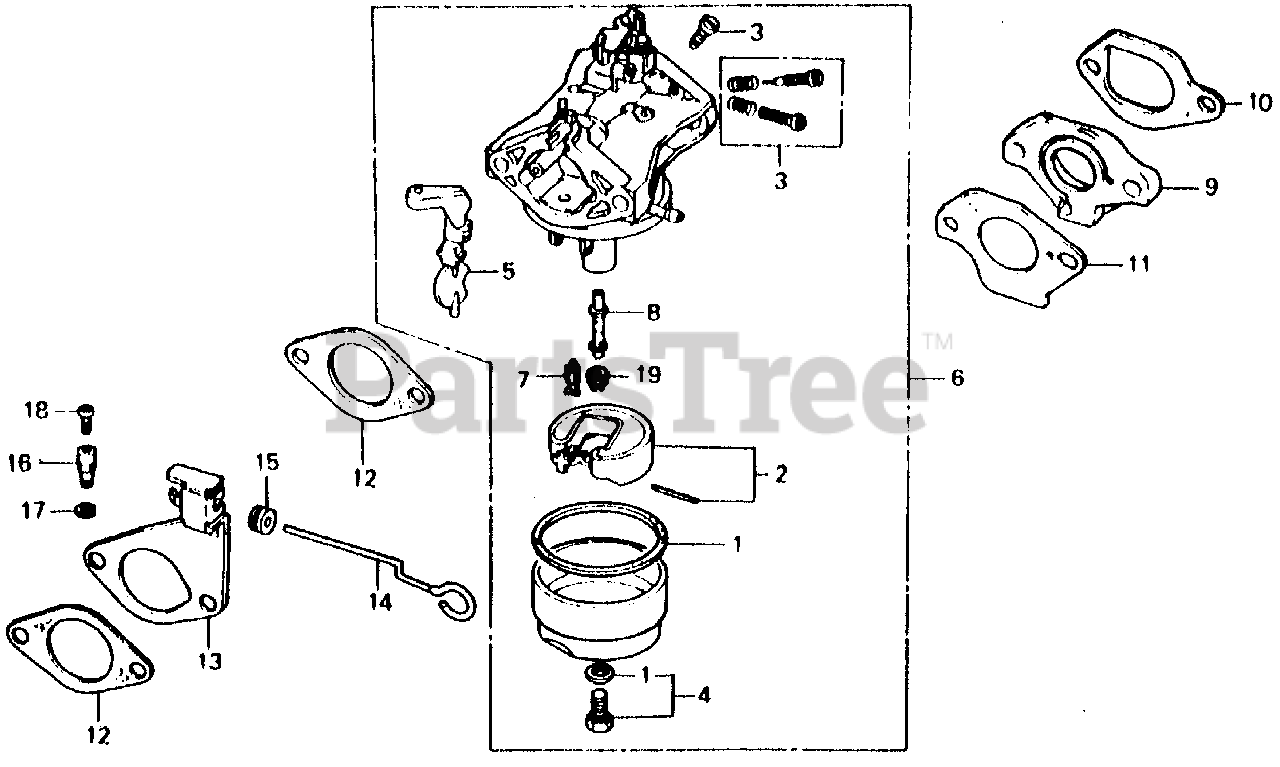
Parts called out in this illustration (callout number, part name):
1	GASKET SET
3	SCREW SET A
3	SCREW SET A (NOT AVAILABLE)
4	SCREW SET B
6	CARBURETOR ASSY.
6	CARBURETOR ASSY. (BB33C D)
7	VALVE, FLOAT
8	NOZZLE, MAIN
9	INSULATOR, CARBURETOR
10	GASKET, INSULATOR
11	GASKET, CARBURETOR
12	GASKET, AIR CLEANER
13	STAY, CHOKE CONTROL
14	ROD, CHOKE CONTROL
15	GROMMET, CHOKE ROD
16	HOLDER, CABLE
17	CIRCLIP (5MM)
18	SCREW, PAN (4X8)
19	JET, MAIN (#75)
19	JET, MAIN (#78)
19	JET, MAIN (#80)
19	JET, MAIN (#82)
19	JET, MAIN (#85)
